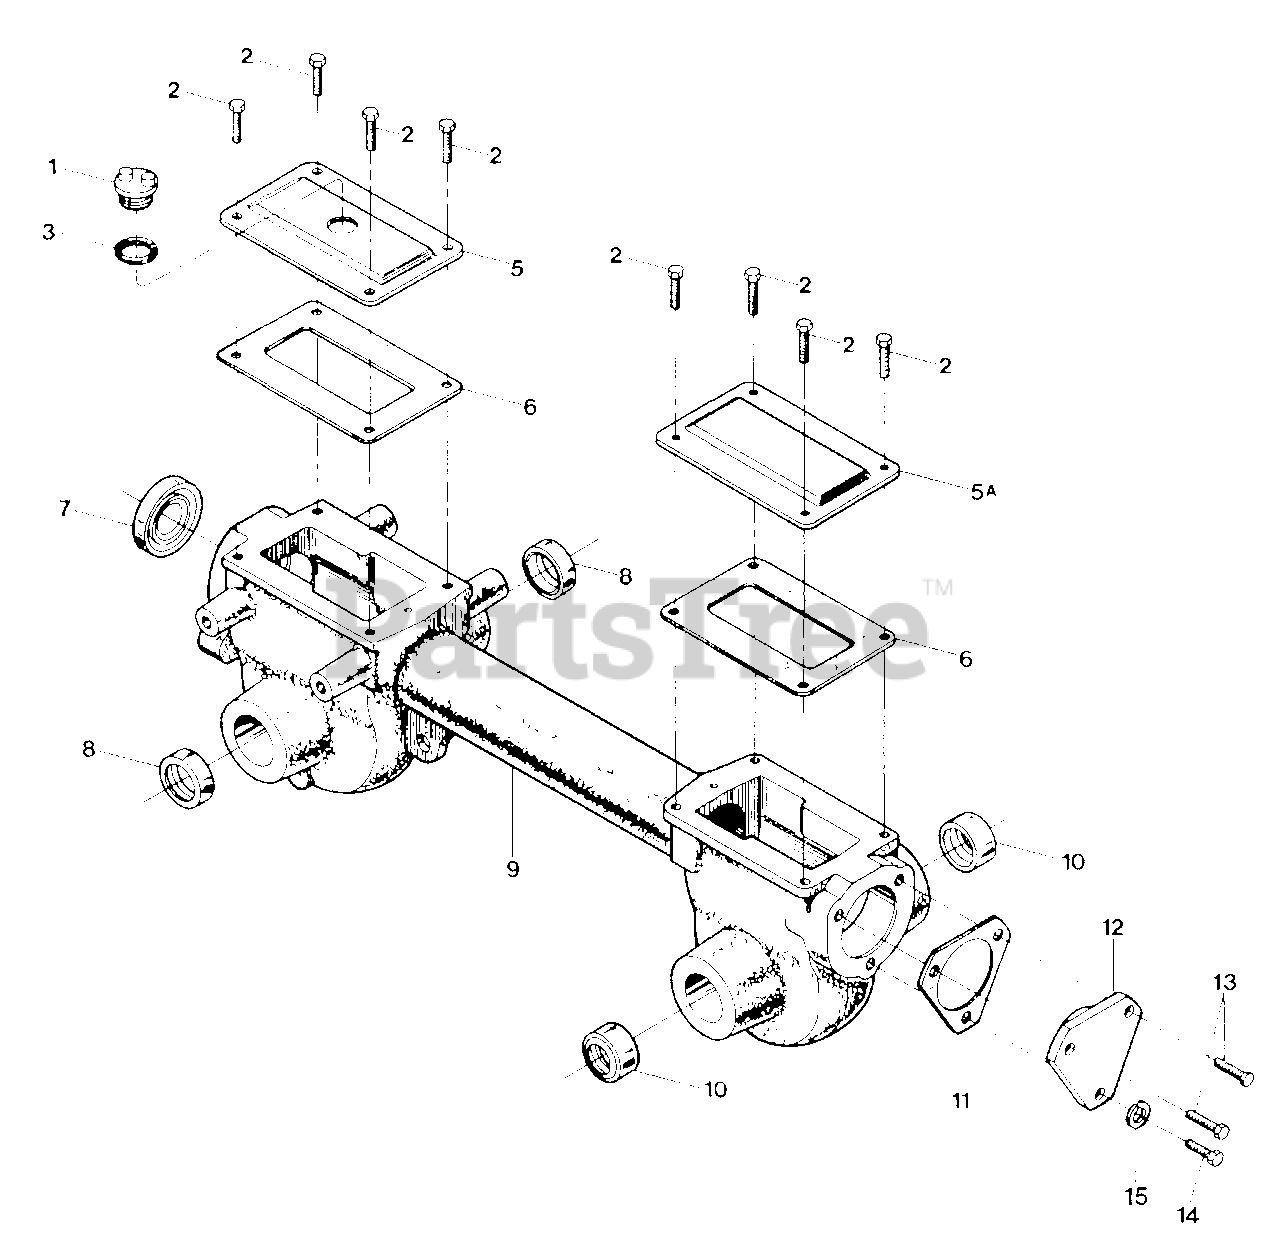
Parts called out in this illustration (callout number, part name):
1	Plug - Transmission Oil Fill/Check
2	Bolt - Hex Hd., Flange Lock, 5/16-18 x 5/8", GR5
3	Gasket - Transmission Oil Fill/Check Plug
5	Cover - Transmission Housing Front
5A	Cover - Transmission Housing, Rear
6	Gasket - Transmission Housing Cover
7	Oil Seal - Driveshaft
8	Oil Seal - Wheelshaft
9	Transmission Case, Rear Housing and Tube Assembly
10	Oil Seal - Tine Shaft
11	Gasket - Bearing Cap
12	Cap - Rear Bearing
13	Bolt - Flanged Hd., 5/16-18 x 1"
14	Bolt - Flanged Hd., 5/16-18 x 3/4"
15	Lockwasher, 5/16"
